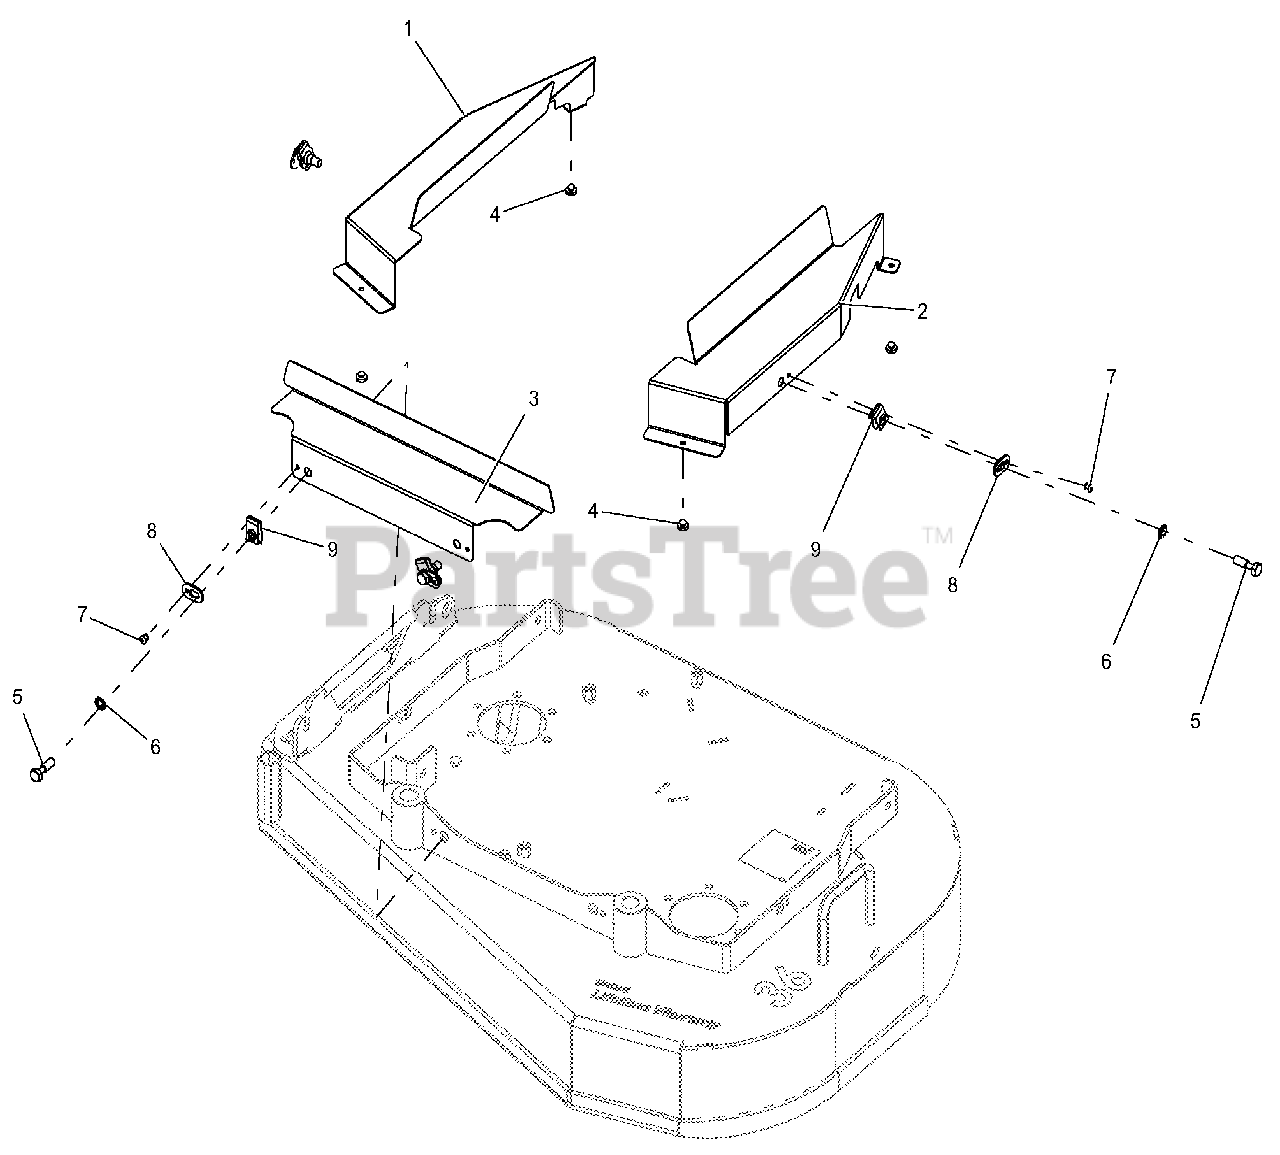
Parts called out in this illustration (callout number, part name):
1	GUARD, BELT 36" LH CE-RED
2	GUARD, BELT LH CE 36
3	GUARD, BELT 36" CE CENTER-RED
4	BUMPER GROMMET .125 X .25 REV
5	BLT, HEX 0.38-16 X 1.25 GR5 CAPTIVE
6	LOCK, WSHR-EXT 0.391 X 0.628 X 0.036 YWZC
7	RVT-POP .187x.250 (#64) YWZC
8	KEEPER, BOLT
9	NUT, RTNR .375-16X.37
